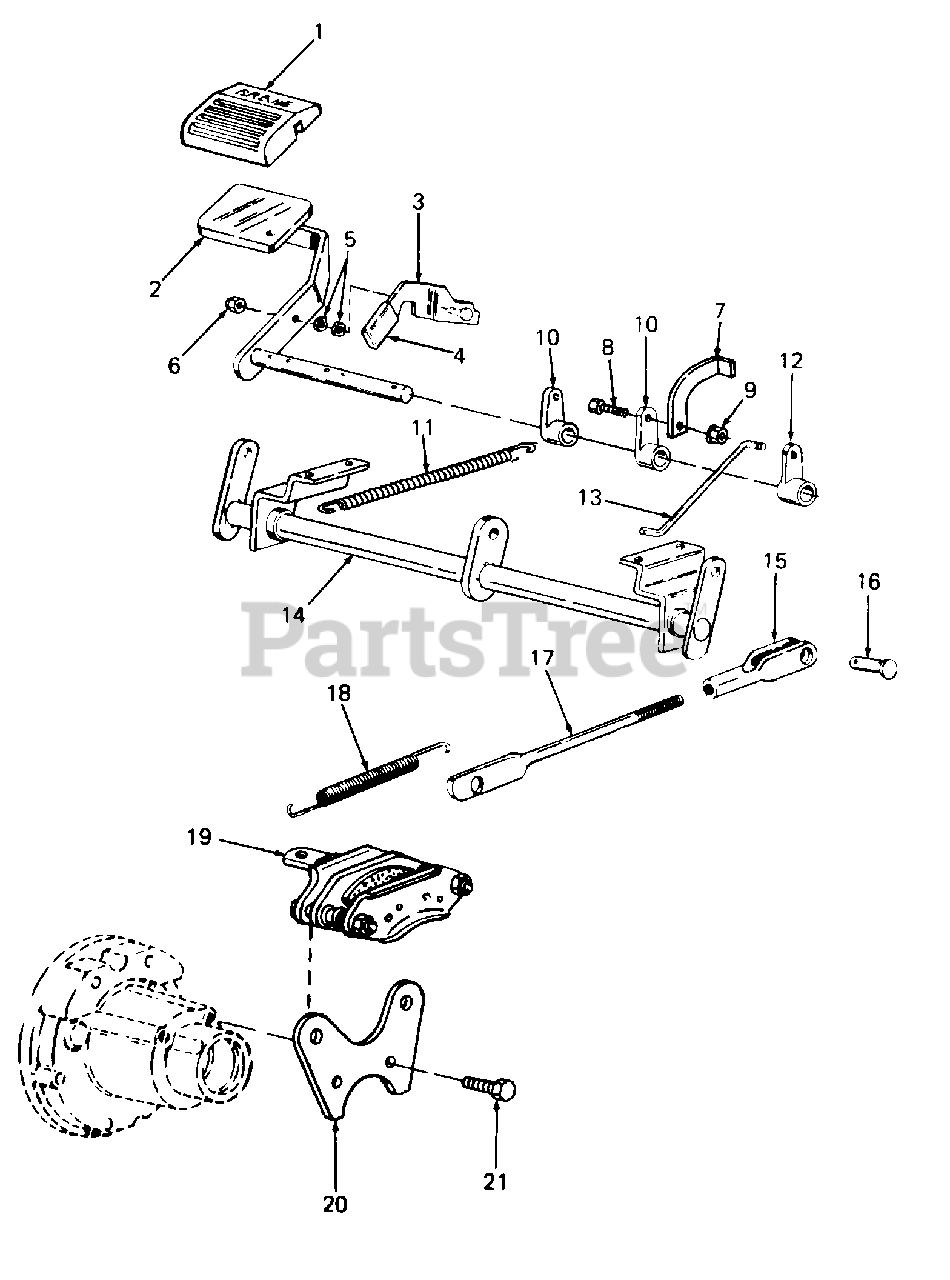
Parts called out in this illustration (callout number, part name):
1	Pad, Brake Pedal
2	Pedal Assy, Brake
5	Washer, Wave, 1/4 Dia
6	Nut, Hex Insert Lock, 1/4-20
8	Screw, Hex Cap, 3/8-16 X .75 Lg GR5
9	Nut, Hex Flanged Lock, 3/8-16 GR5
11	Spring, Return
15	Clevis, Adjustment
16	Pin, Clevis, 3/8 Dia X 1.0 Lg
17	Rod, Brake
18	Spring, Tension
19	Kit, Brake Caliper
20	Bracket, Brake Mounting
21	Screw, Hex Cap, 5/16-18 X 1.O Lg GR5
